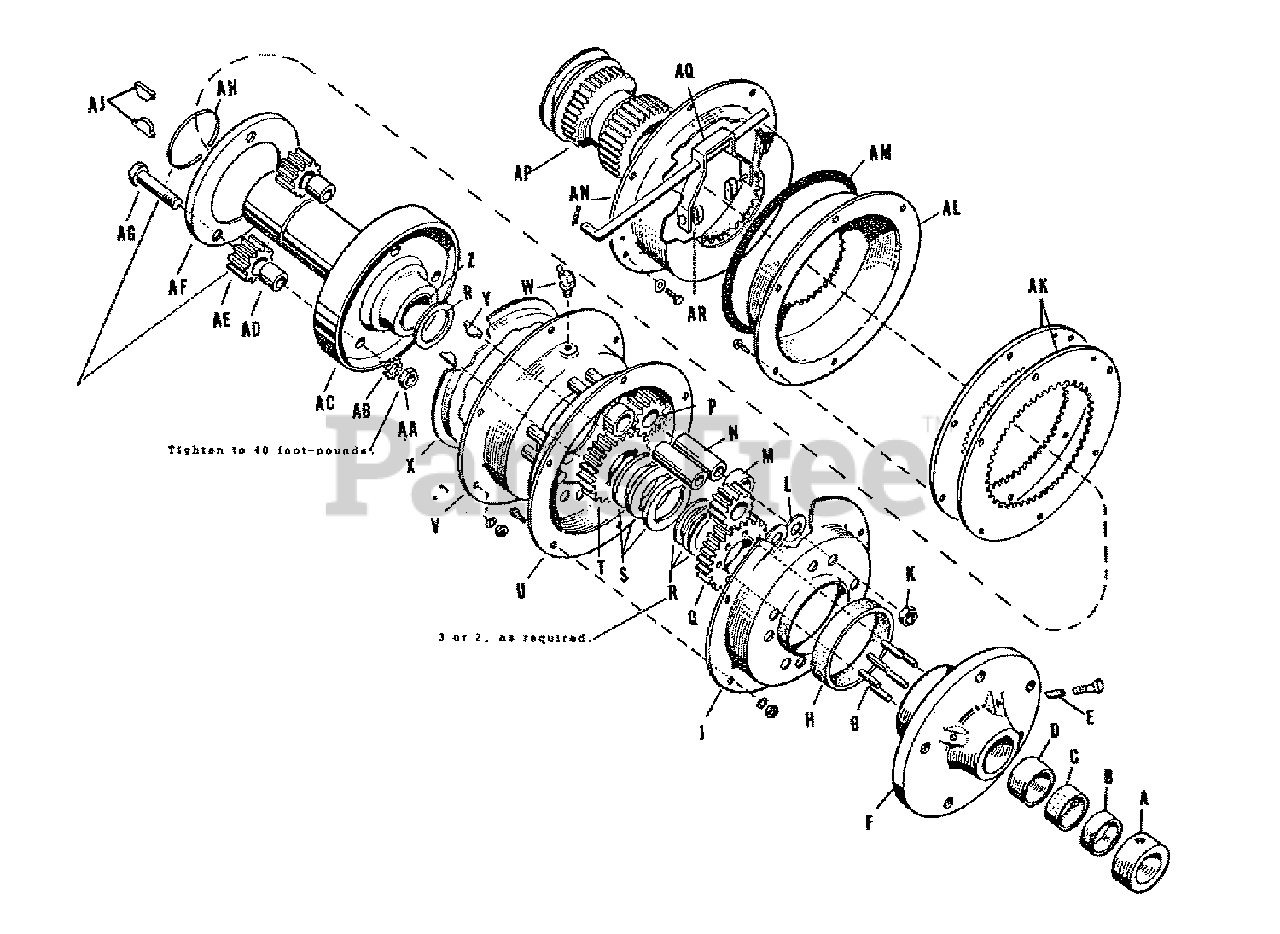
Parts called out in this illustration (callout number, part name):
A	COLLAR, Axle
C	BEARING, Nylon
F	HUB, R.H. Wheel
G	PIN, Roll
H	SEAL, Differential Cover
J	COVER, Differential
K	NUT, Lock, Full Hexagon, 3/8-24
L	WASHER, Plain, 5/16
M	SPACER, Differential
N	SPINDLE, Pinion, Differential
P	PINION, Differential
Q	GEAR, Differential
S	WASHER, Axle
T	GEAR, Differential
U	COVER, Differential
V	CARRIER ASSEMBLY
W	FITTING, Grease, Alemite #1637
X	PLATE, Thrust
Y	KEY, Hi-Pro, HP-608
AA	NUT, Lock, Full Hexagon, 3/8-24
AB	LOCKWASHER, External Shakeproof
AC	SPIDER ASSEMBLY
AD	SPACER, Pinion
AF	RING, Bolt
AG	BOLT, Hex Head
AH	SNAP, Ring
AK	GEAR, Rign
AL	COVER ASSEMBLY
AM	SEAL, Housing Assembly
AN	HOUSING ASSEMBLY
AP	GEAR ASSEMBLY, Sun
AQ	CLEVIS ASSEMBLY
AR	BLOCK, Shift
